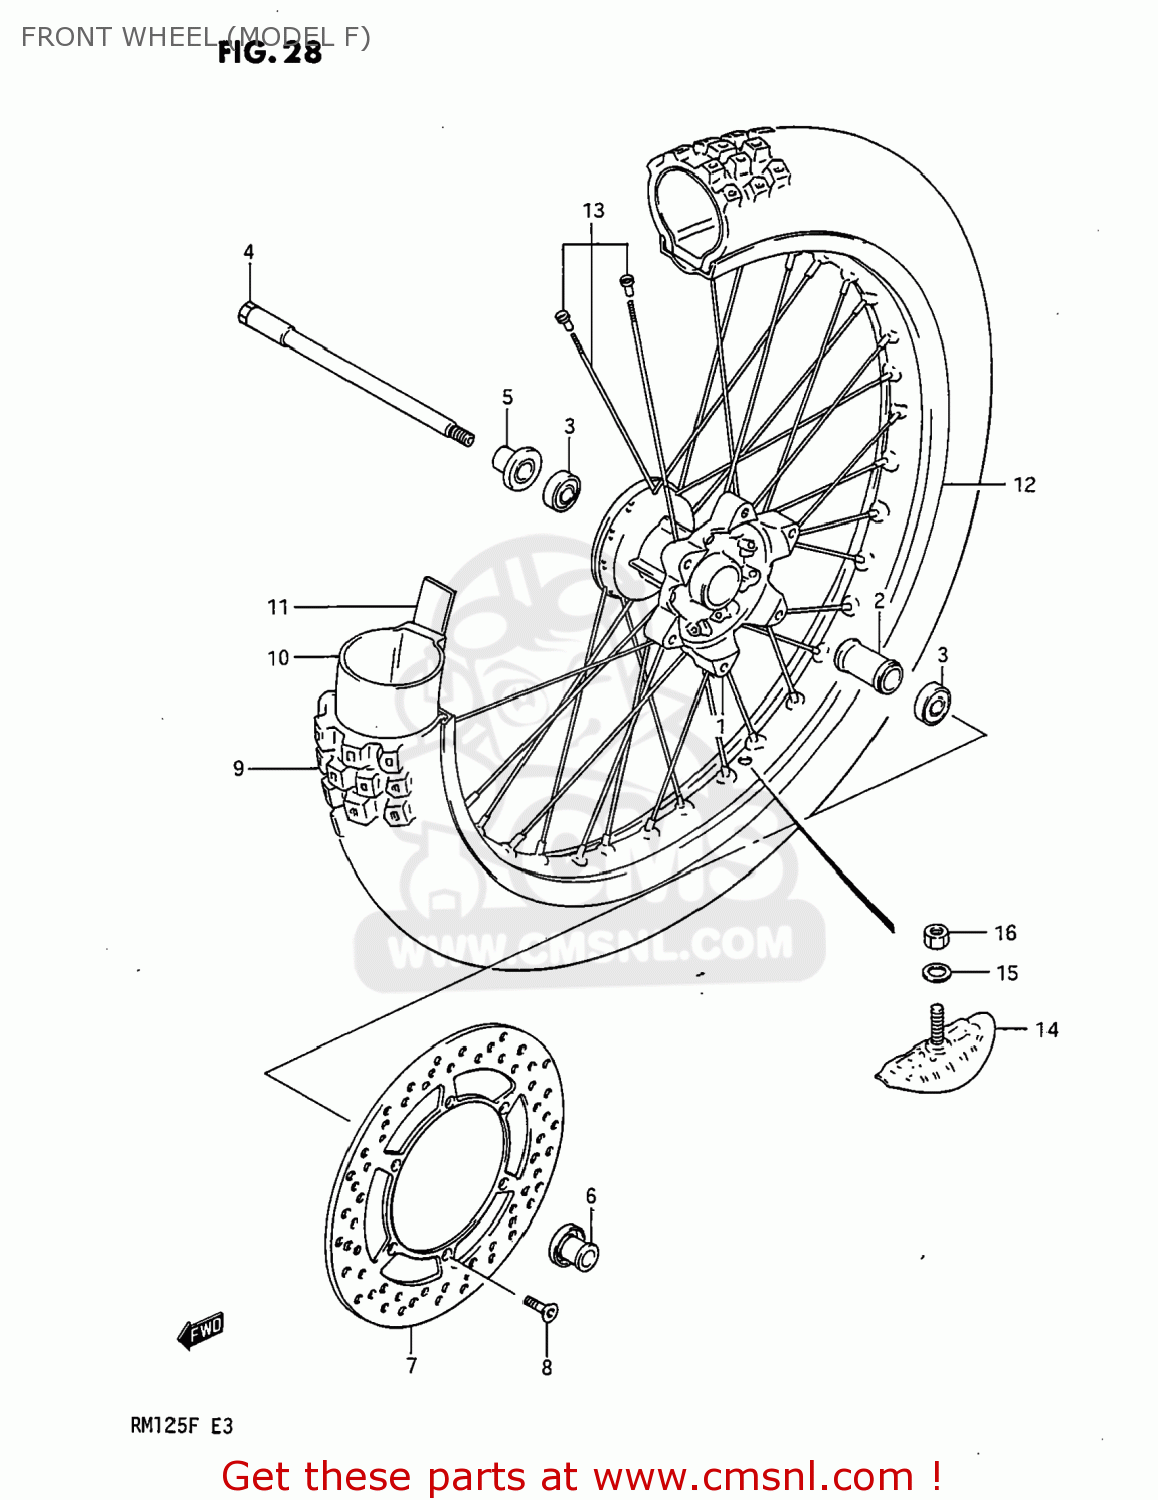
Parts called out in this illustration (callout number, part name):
1	HUB,FRONT
2	SPACER,FRONT HUB BEARING
3	BEARING
4	AXLE,FRONT
5	SPACER,FRONT AXLE,RIGHT
6	SPACER,FRONT AXLE,LEFT
7	DISC,BRAKE
8	SCREW
9	TIRE,FRONT
10	TUBE,INNER
11	PROTECTOR,WHEEL INNER
12	RIM,FRONT WHEEL (1.60X21)(
13	SPOKE SET,FRONT
14	STOPPER,BEAD
15	WASHER
16	NUT
